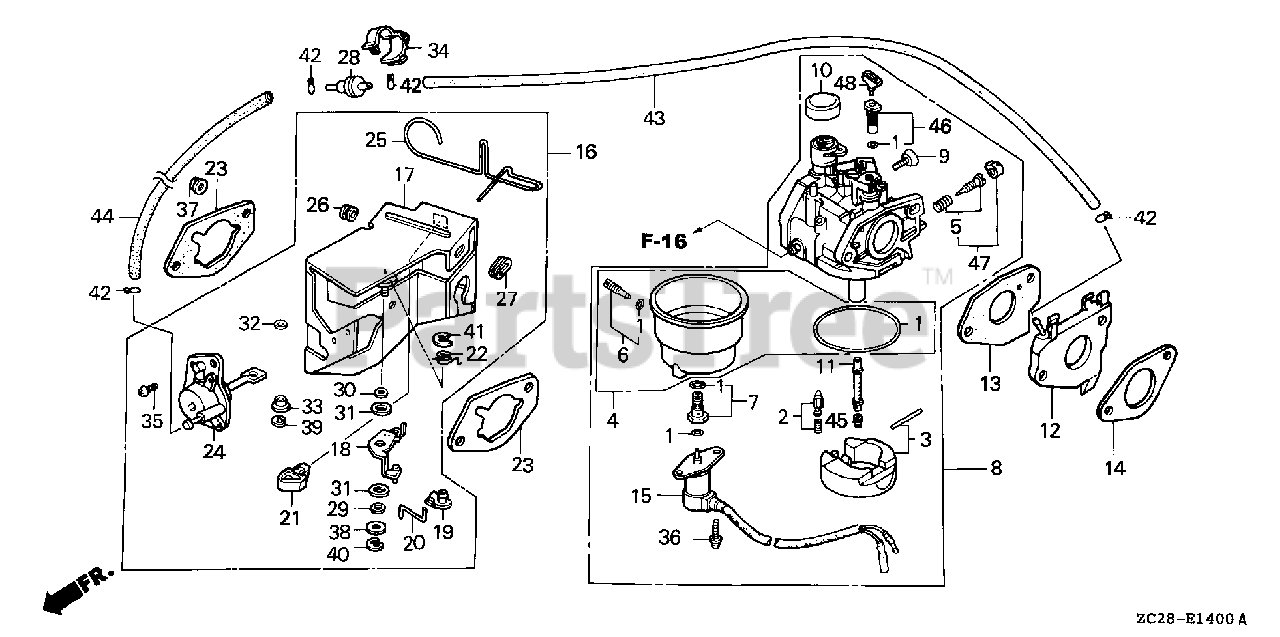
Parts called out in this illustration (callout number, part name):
1	GASKET SET
2	VALVE SET, FLOAT
4	CHAMBER SET, FLOAT
5	SCREW SET, PILOT
6	SCREW SET, DRAIN (CARBURETOR NO.)
8	CARBURETOR ASSY. (BE37A B)
8	CARBURETOR ASSY. (BE37A C)
8	CARBURETOR ASSY. (BE37A D)
9	SCREW, THROTTLE STOP
10	CAP, CHOKE LEVER DUST
11	NOZZLE, MAIN
12	INSULATOR, CARBURETOR
13	GASKET, CARBURETOR
14	GASKET, INSULATOR
15	VALVE ASSY., SOLENOID
16	STAY ASSY., MANUAL CHOKE
17	STAY, SOLENOID (NA USE ALT:04103-ZE2-702)
17	STAY, SOLENOID
18	DIAPHRAGM SET, CHOKE STAY
18	LEVER, CHOKE
19	JOINT, ROD
20	DIAPHRAGM SET, CHOKE STAY
20	ROD, CHOKE
21	STOPPER, CHOKE ROD
22	SPRING, MANUAL CHOKE (NA USE ALT:04103-ZE2-702)
22	SPRING, MANUAL CHOKE
23	GASKET, AIR CLEANER
24	DIAPHRAGM ASSY.
24	DIAPHRAGM ASSY. (NA USE ALT:04103-ZE2-702)
25	DIAPHRAGM SET, CHOKE STAY
25	ROD, CHOKE CONTROL
26	GROMMET, CHOKE ROD
27	GUIDE, CHOKE ROD
28	VALVE, DASHPOT CHECK
29	BUSH, ARM PIVOT
30	WASHER, CHOKE LEVER
31	SEAL, CHOKE LEVER
32	WASHER, THRUST (2.7X8)
33	COLLAR, LEVER
34	CLIP, WIRE HARNESS
35	SCREW, PAN (5X12)
36	SCREW-WASHER (5X12)
37	NUT, FLANGE (6MM)
38	WASHER, PLAIN (5MM)
39	E-RING (2MM)
40	E-RING (4MM)
41	E-RING (7MM)
42	CLIP, TUBE (B7)
43	BULK HOSE, VACUUM (3.5X8000) (3.5X75)
44	BULK HOSE, VACUUM (3.5X8000) (3.5X130)
45	JET, MAIN (#92)
45	JET, MAIN (#95)
45	JET, MAIN (#98)
46	JET SET, PILOT (#38)
